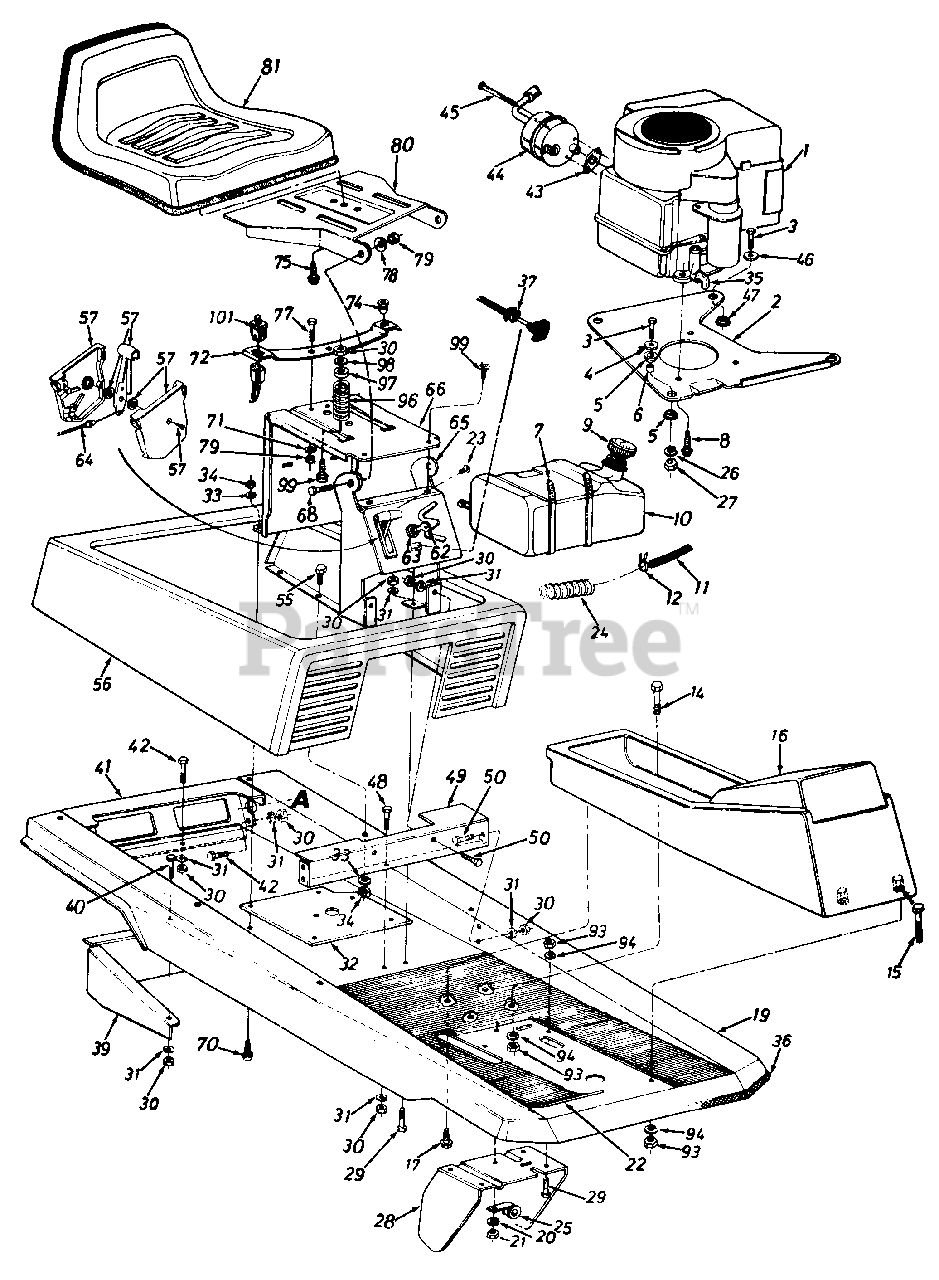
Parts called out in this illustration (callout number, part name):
1	Engine
4	Fl-Wash. .330" I.D. x 1.125" O.D.
5	Engine Mounting Grommet
6	Spacer .315" I.D. x .50" O.D. x.520" Lg.
7	Cable Tie 30.6 Lg.
8	Hex Wash. Hd. Self-Tap Scr. 3/8-16 x 1.25" Lg.
9	Gas Gauge
10	Fuel Tank
11	Gas Line 26 Inches
12	Hose Clamp 1/2" O.D. Tube
14	Hex Bolt 5/16-18 x 1.75" Lg.
15	Hex Bolt 5/16-18 x 2.0" Lg.
16	Front Console
17	Plastite Scr. 5/16 x 1.25" Lg.
19	Main Frame
20	L-Wash. 5/16" I.D.
21	Hex Nut 5/16-18 Thd.
22	Floor Mat
23	Truss Mach. AB-Tap Scr. #10 x .50" Lg.
24	Convoluted Conduit
25	Clamp
26	L-Wash. 5/16" I.D.
27	Hex Nut 5/16-24 Thd.
28	Clutch-Brake Pedal Ass'y.
29	Hex Bolt 5/16-18 x .75" Lg
30	Hex Nut 5/16-18 Thd.
31	L-Wash. 5/16" I.D.
32	Mounting Brkt. Variable Speed Pulley
33	L-Wash. 1/4" I.D.
34	Hex Nut 1/4-20 Thd.
35	90ø Elbow Male To Female
36	Trim Strip 18" Lg.
37	Choke Control
43	Exhaust Gasket
44	Muffler Ass'y.
45	Shld. Bolt
46	Fl-Wash. .33" I.D. x 1.25" O.D.
47	Flange Wash. .32" I.D. x .75" O.D.
48	Hex Bolt 5/16-18 x .75" Lg.
49	Seat Support & Frame Brkt.
50	Hex Bolt 5/16-18 x .75" Lg.
55	Hex Bolt 1/4-20 x .50" Lg.
56	Engine Cover Ass'y.
57	Throttle Control Box Ass'y.
62	Ignition Key
63	Ignition Switch
64	Throttle Control Wire
68	Hex Bolt 5/16-18 x .75" Lg.
70	Hex Tap Scr. 1/4-20 x 1.0 Lg.
71	L-Wash. 5/16" I.D.
72	Seat Spring
74	Grommet
75	Hex Wash. Hd. Tap Scr. 3/8-16 x 3/4" Lg.
77	Hex Bolt 5/16-18 x 75" Lg.
78	Bell-Wash. .345" I.D. x .88" O.D.
79	Hex Cent. L-Nut 5/16-18 Thd.
80	Seat Pivot Bracket
81	Seat Ass'y. Comp.
93	Hex Nut 5/16-18 Thd.
94	L-Wash. 5/16" I.D.
96	Compression Spring 2.61" Lg.
97	Bushing
98	Fl-Wash. .344" I.D. x .875"
99	Hex Bolt 5/16-18 x 1" Lg. (Grade 5)
101	Seat Switch
